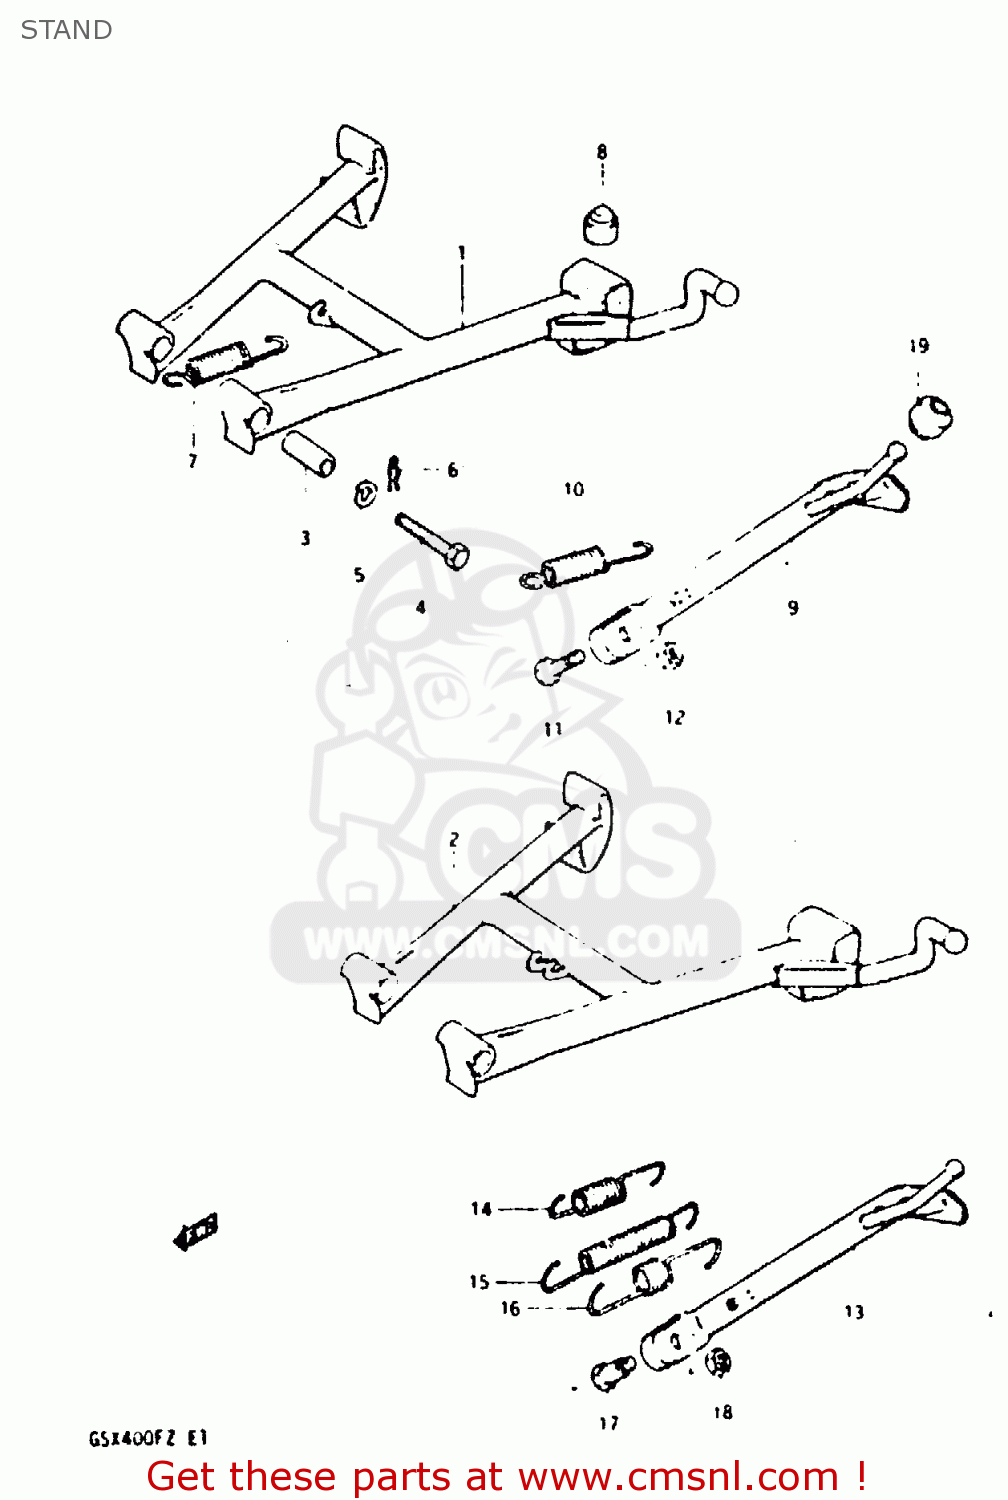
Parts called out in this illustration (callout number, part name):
1	STAND, CENTER
3	SPACER(10X16X38.8)
4	BOLT
5	LOCK WASHER
6	CLIP
7	SPRING
8	CUSHION
9	STAND, PROP
10	SPRING
11	BOLT(10X30)
12	NUT
19	CUSHION
